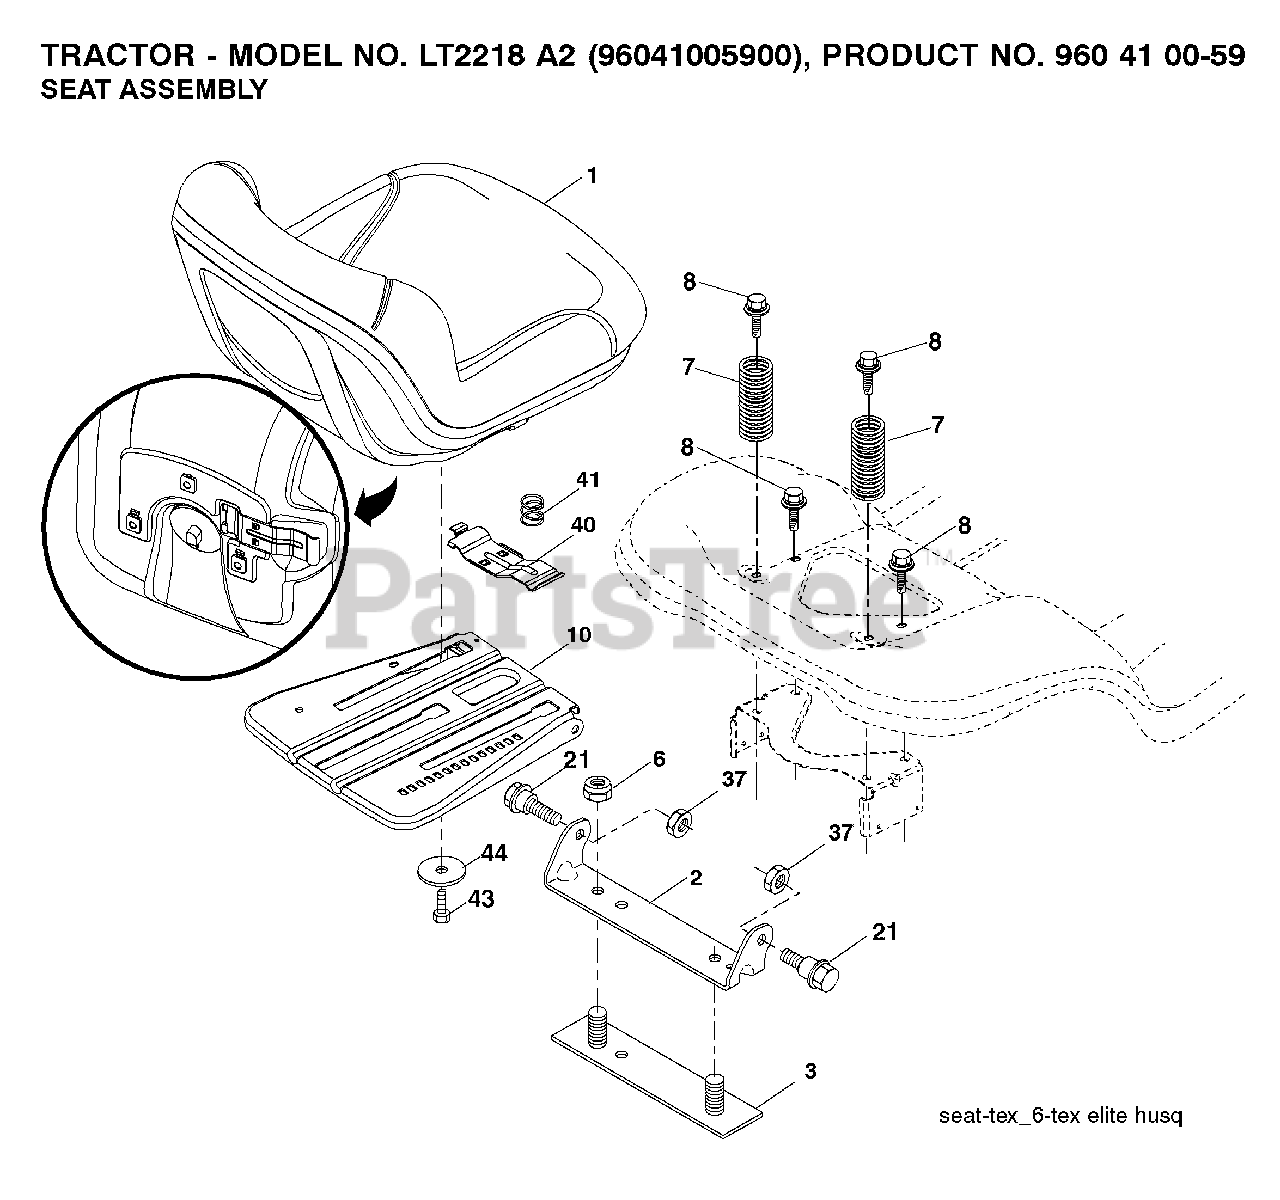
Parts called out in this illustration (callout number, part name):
1	SEAT.TG150.BLK.NLOGO.
2	BRKT.PIVOT.FENDER
6	NUT
7	SPRING COMPRESSION
8	BOLT, 5/16-18 X 1 3/4
10	PAN.ASM.SEAT.3PT
21	BOLT.SHOULDER.5/16-18
37	NUT.71038.31-18.HEX.NYLOCK
40	HANDLE.SLIDE.SEAT.TEX.BLACK
41	SPRING.LATCH.SEAT.TEX
44	WASHER 13/32 X 2-3/8 X 12GA
